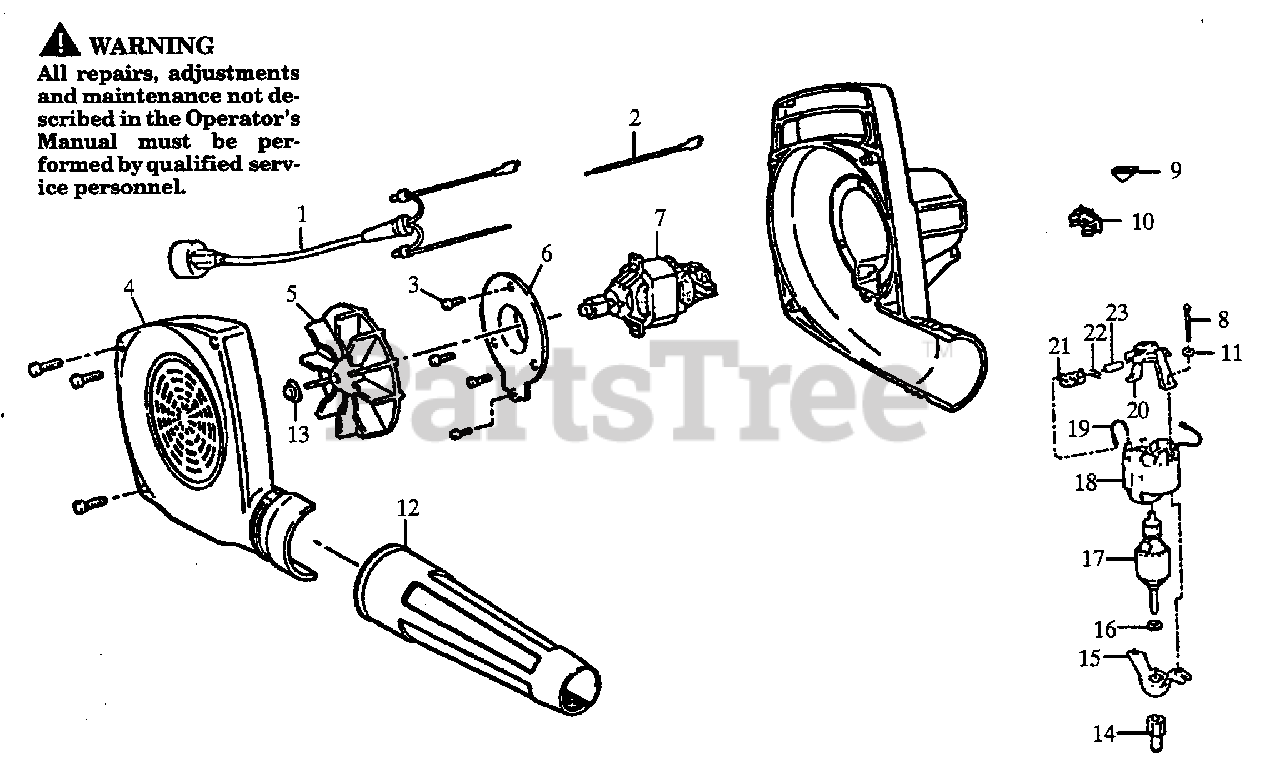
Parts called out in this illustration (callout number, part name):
1	Harness Ass'y.
2	Leadwire Ass'y.
4	Housing (Set)
5	Impeller
6	Mounting Plate
7	Motor/Adapter Ass'y.
9	Switch Cover
10	Switch Ass'y.
11	Lockwasher
12	Nozzle Tube
13	Push Nut
14	Impeller Adapter
15	Endbell Ass'y. (Drive)
16	Thrust Washer
17	Armature Ass'y.
18	Field Ass'y.
19	Wire/Terminal Ass'y.
20	Endbell Ass'y. (Brush)
21	Brush Holder
22	Brush Spring
